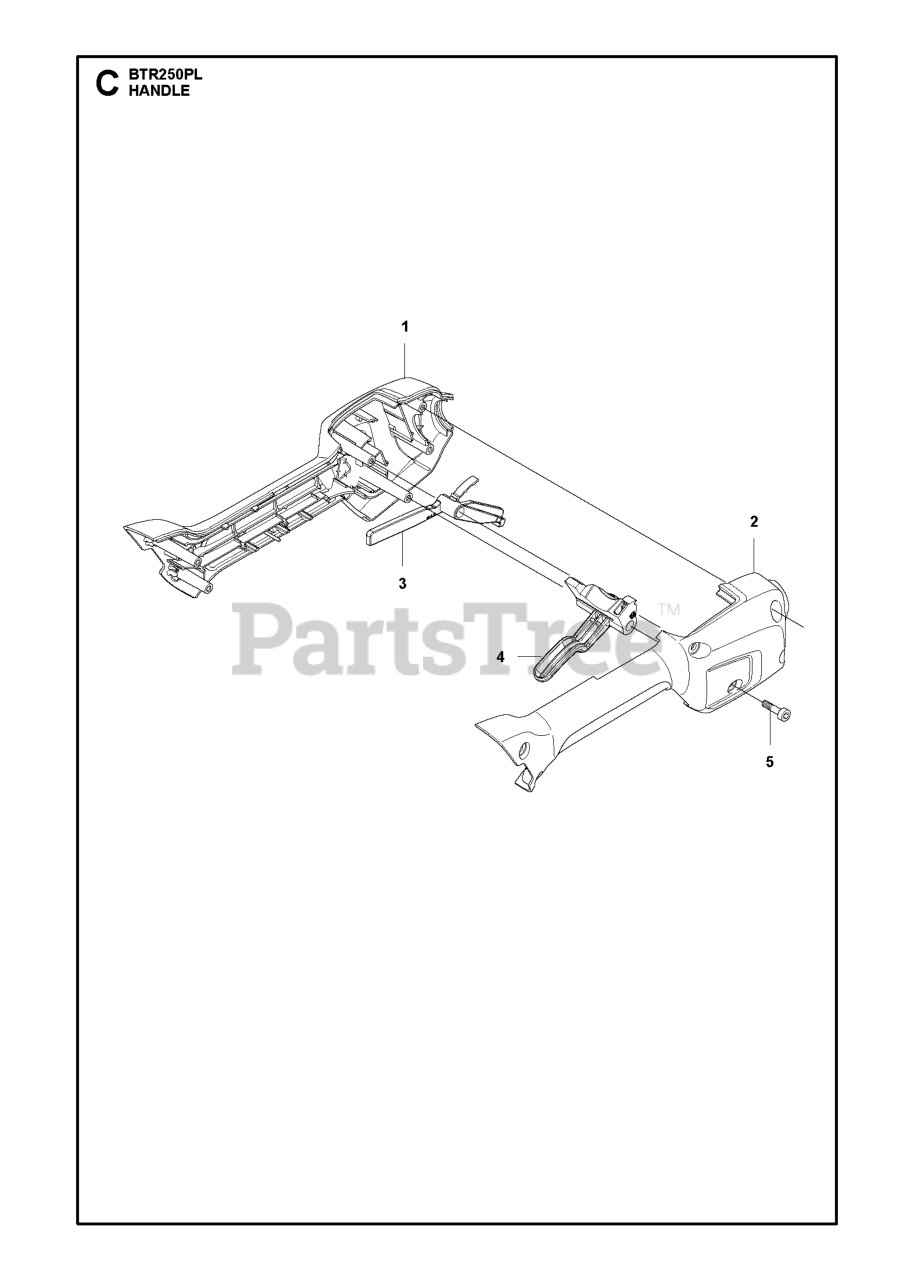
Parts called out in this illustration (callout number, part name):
1	HANDLE LEFT
2	HANDLE RIGHT
3	THROTTLE LOCKOUT BLACK
4	THROTTLE LOCKOUT ZENOAH-RED (
